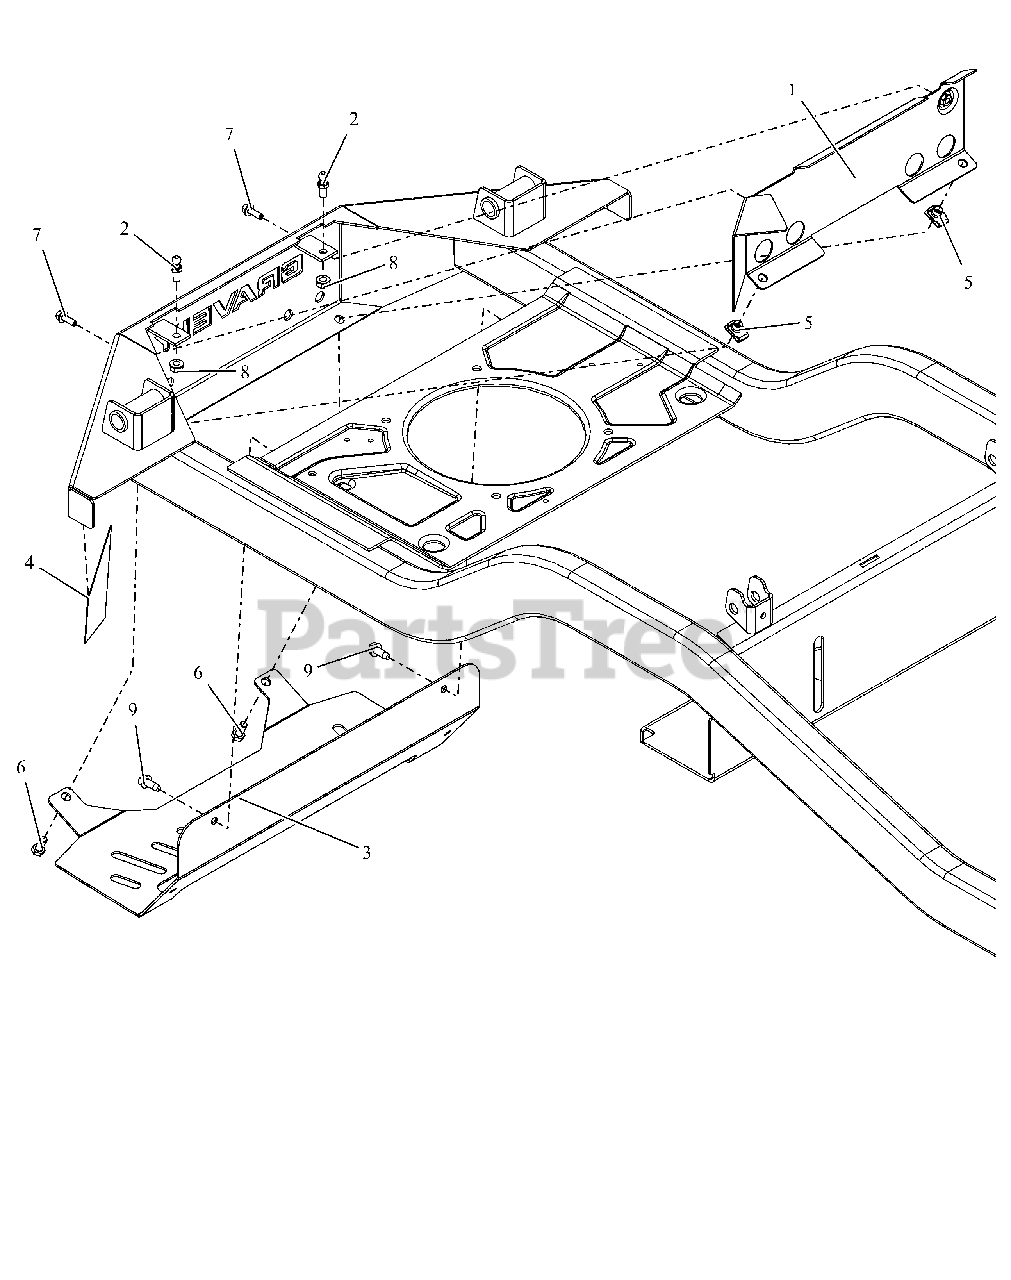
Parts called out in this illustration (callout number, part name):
1	WMT, HEAT BAFFLE
2	STUD- BALL
3	SHIELD, HEAT (HD)
4	TAPE, HEAT DEFLECTOR
5	NUT-CLIP RETAINER 5/16-18X.56
6	BLT,HEX .31-18X.75 G5 ZCC
7	BLT,HEX-FLG .25-20X.75 G5 BFP
8	NUT,LK-CTR-FLG .31-18 GF ZCC
9	SCR,TAP .312-18X.75 HWH TR ZCC
